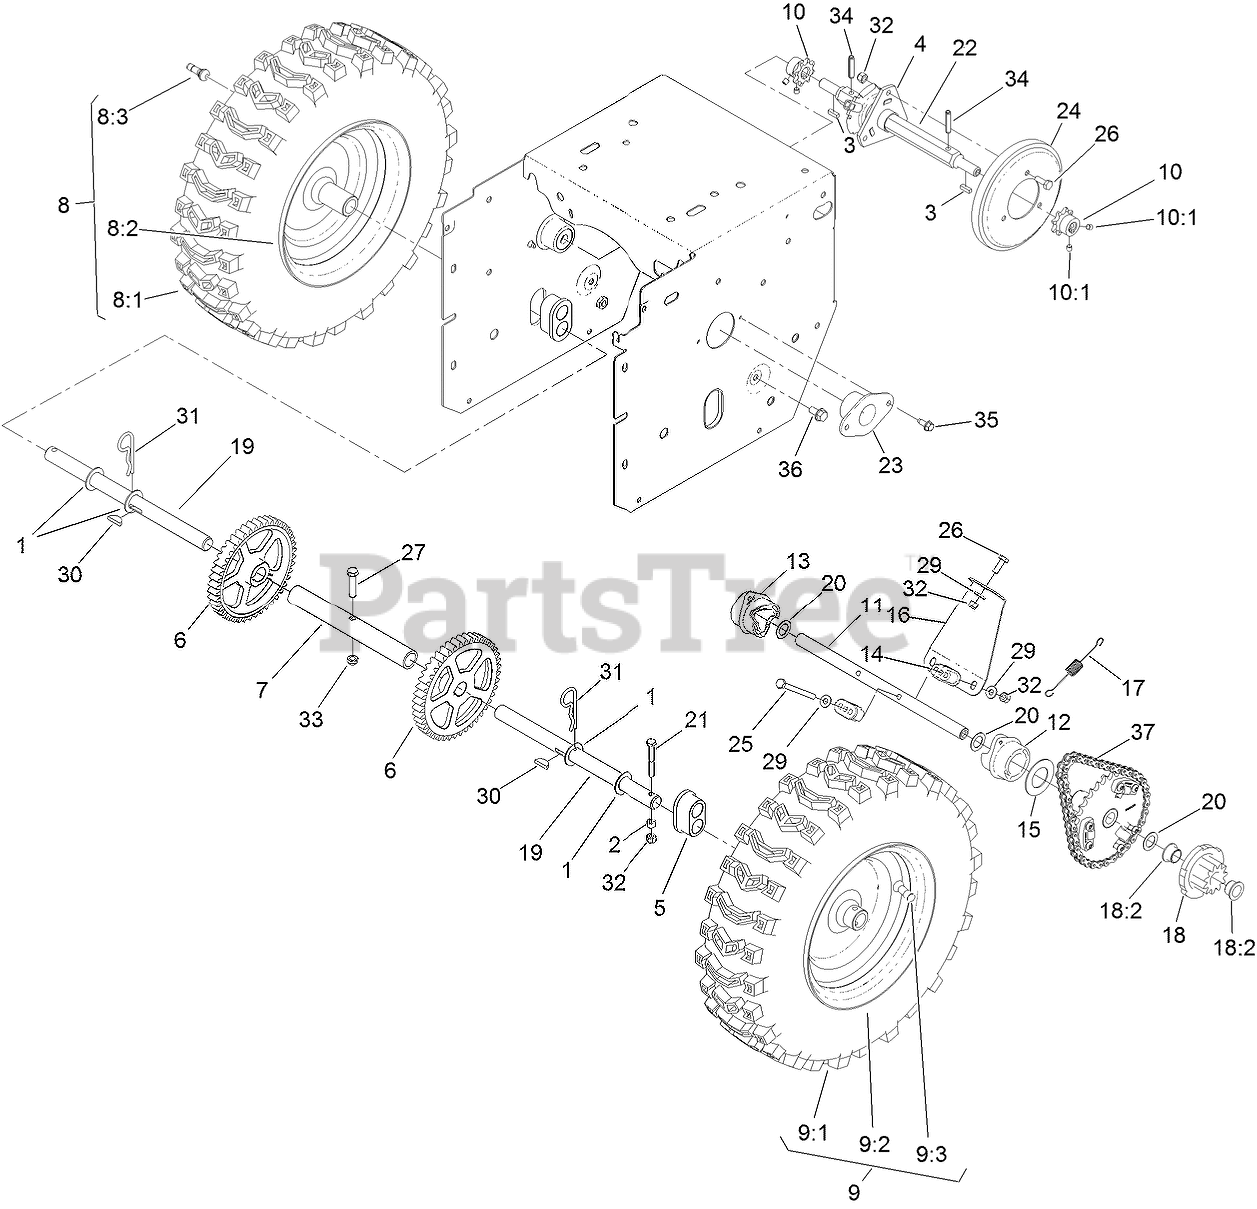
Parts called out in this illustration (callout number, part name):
1	WASHER-THRUST
2	SPACER-BLADE, ROTOR
3	KEY-SQUARE
4	TRUNNION-HEX
5	BEARING-AXLE
6	GEAR-AXLE, 44 TOOTH
7	TUBE-AXLE
8	RH WHEEL AND TIRE ASM
8:1	RIM-TIRE
8:3	STEM-VALVE
9	LH WHEEL AND TIRE ASM
9:1	RIM-TIRE
9:3	STEM-VALVE
10	SPROCKET-8 TOOTH
10:1	SCREW-HSH
11	SHAFT-INTERMEDIATE
12	COLLAR-SHIFT, LH
13	COLLAR-SHIFT, RH
14	GUIDE-COLLAR
15	WASHER-THRUST
16	BRACE-COLLAR, SHIFT
17	SPRING-EXTENSION
18	11T GEAR ASM
18:2	BUSHING-FLANGE
19	SHAFT-AXLE
20	WASHER-FLAT
21	SCREW-HH
22	SHAFT-HEX
23	RETAINER-BEARING
24	WHEEL-FRICTION
25	SCREW-HH
26	SCREW-HH
27	SCREW-HH
29	WASHER-FLAT
30	KEY-WOODRUFF
31	PIN-HAIR
32	NUT-HEX
33	NUT-HEX
34	PIN-ROLL, SLOTTED
35	SCREW-HWH
36	SCREW-HWHTF
37	CHAIN-ROLLER
37	LINK-CONNECTING
